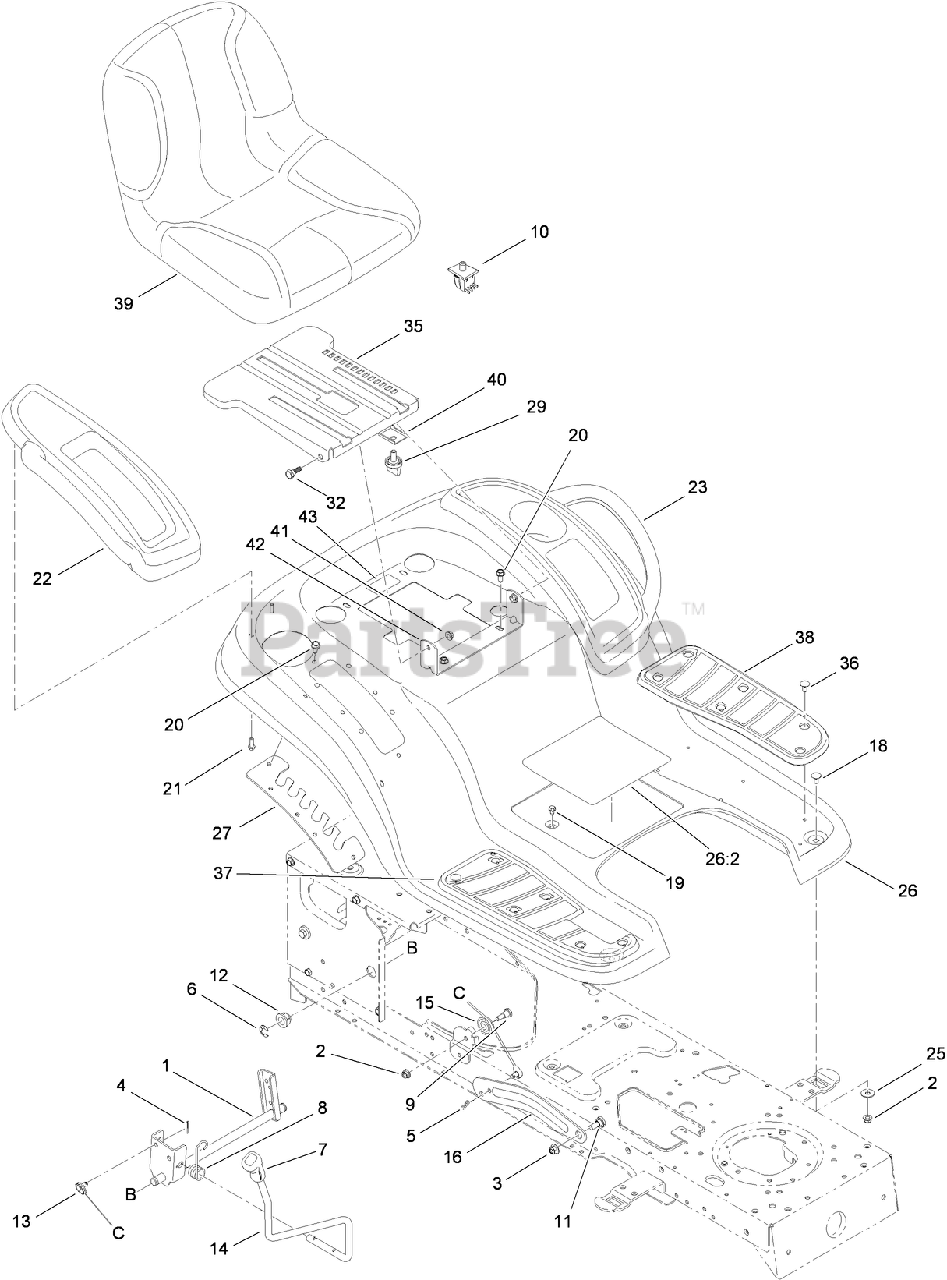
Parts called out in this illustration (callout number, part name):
1	LIFT SHAFT ASM
2	NUT-LOCK, FLANGE
3	NUT-LOCK, FLANGE
4	PIN-COTTER
5	PIN-COTTER
6	RING-E
7	GRIP-HANDLE
8	SPRING-TORSION
9	SPACER
10	SWITCH-SEAT
11	BOLT-SHOULDER
12	BEARING-FLANGE
13	CABLE-LIFT
14	HANDLE-LIFT
15	PULLEY-ROLLER
19	SCREW-HWHTF
20	SCREW-TAP
21	SCREW-TAP
22	COVER-FENDER, RH
23	COVER-FENDER, LH (W/CUPHOLDER)
25	WASHER-FLAT
26	FENDER WITH DECAL
26:2	DECAL-SAFETY
27	BRACKET-ADJUSTING, LIFT
32	BOLT-SHOULDER
35	BRACKET-MOUNT, SEAT
36	CLIP-RATCHET, FASTENER
37	PAD-FOOT, RH
38	PAD-FOOT, LH
39	SEAT-HIGH
40	BRACKET-KNOB, ADJUSTMENT
41	NUT-LOCK, FLANGE
42	BRACKET-PIVOT, SEAT
43	DECAL-TORO HOTLINE
